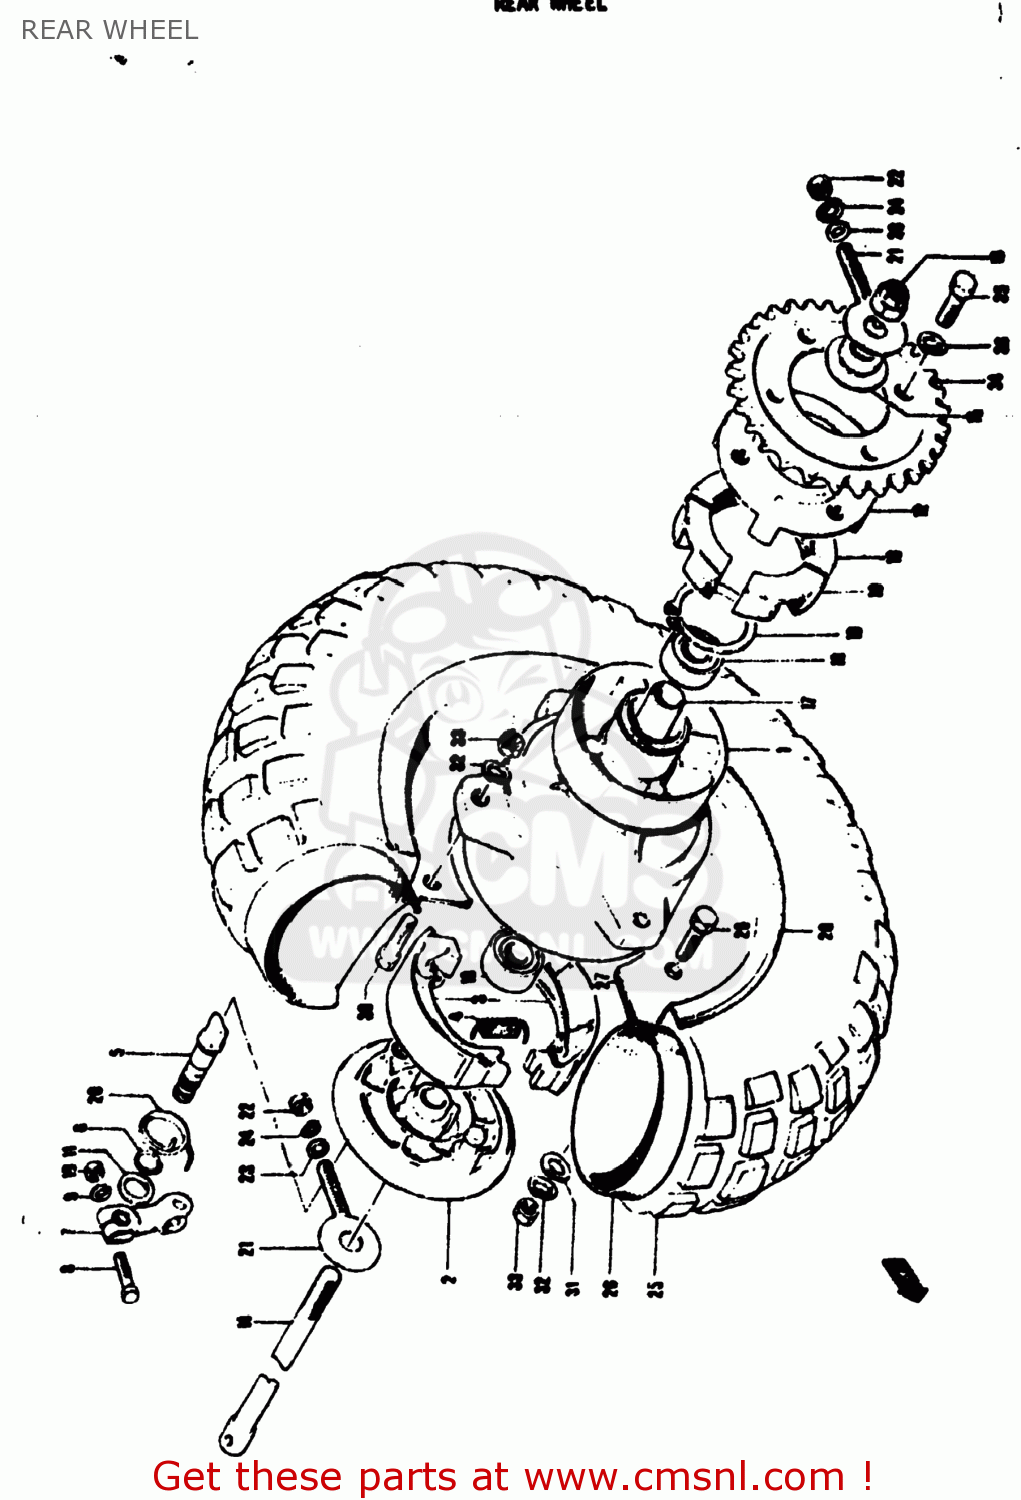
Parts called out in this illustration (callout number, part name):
3	SHOE,BRAKE
4	SPRING(L:34)
5	CAM,FRONT BRAKE
6	O RING(D:2.5,ID:11.4)
7	LEVER,REAR BRAKE CAM
8	BOLT
9	WASHER
10	NUT
11	WASHER(12.5X20X1)
13	CUSHION, REAR HUB
16	NUT
18	BEARING
19	CIRCLIP
20	SPRING
21	ADJUSTER,CHAIN
22	NUT
23	WASHER
24	LOCK WASHER
26	TUBE ASSY,WHL I
29	BOLT
30	HEXAGON BOLT
31	WASHER
32	LOCK WASHER
33	NUT
34	SPROCKET,RR(NT:32)
35	BOLT
36	LOCK WASHER
